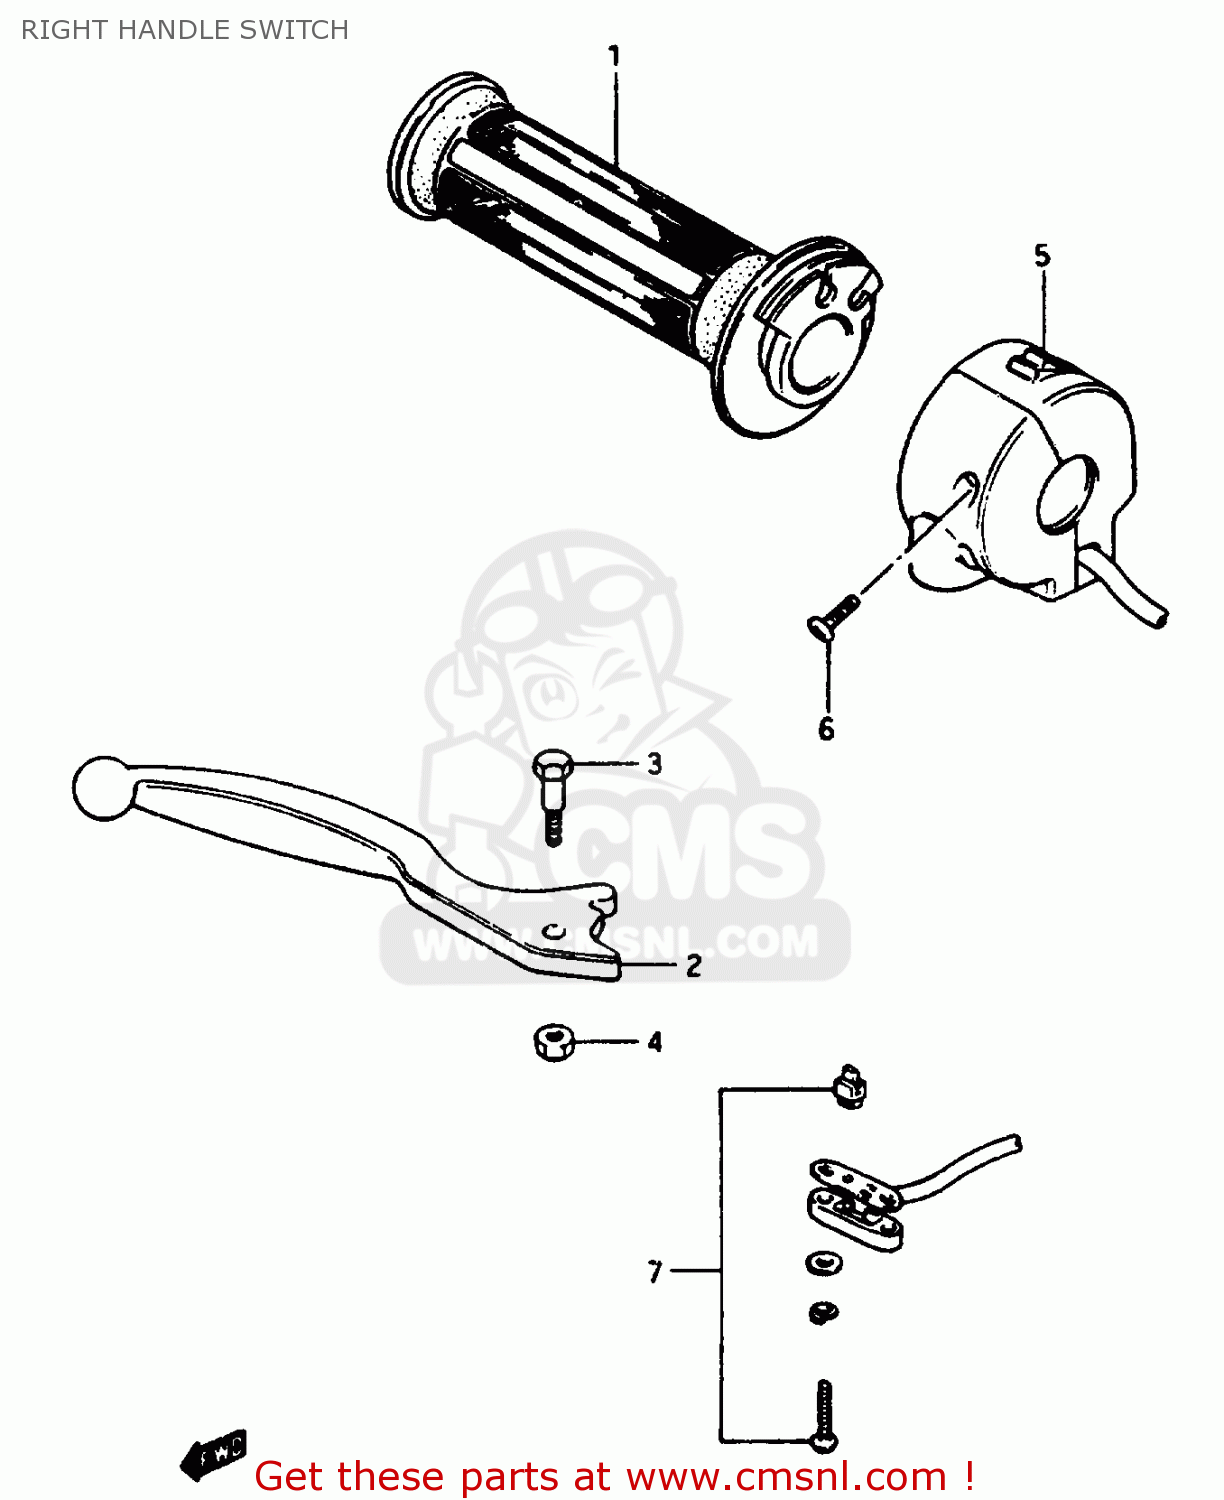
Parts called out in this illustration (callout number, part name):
1	GRIP,THROTTLE
2	LEVER,BRAKE
3	BOLT,LEVER PIVOT
4	NUT
5	SWITCH ASSY, HANDLE RH
6	SCREW
7	SWITCH ASSY,STOP
